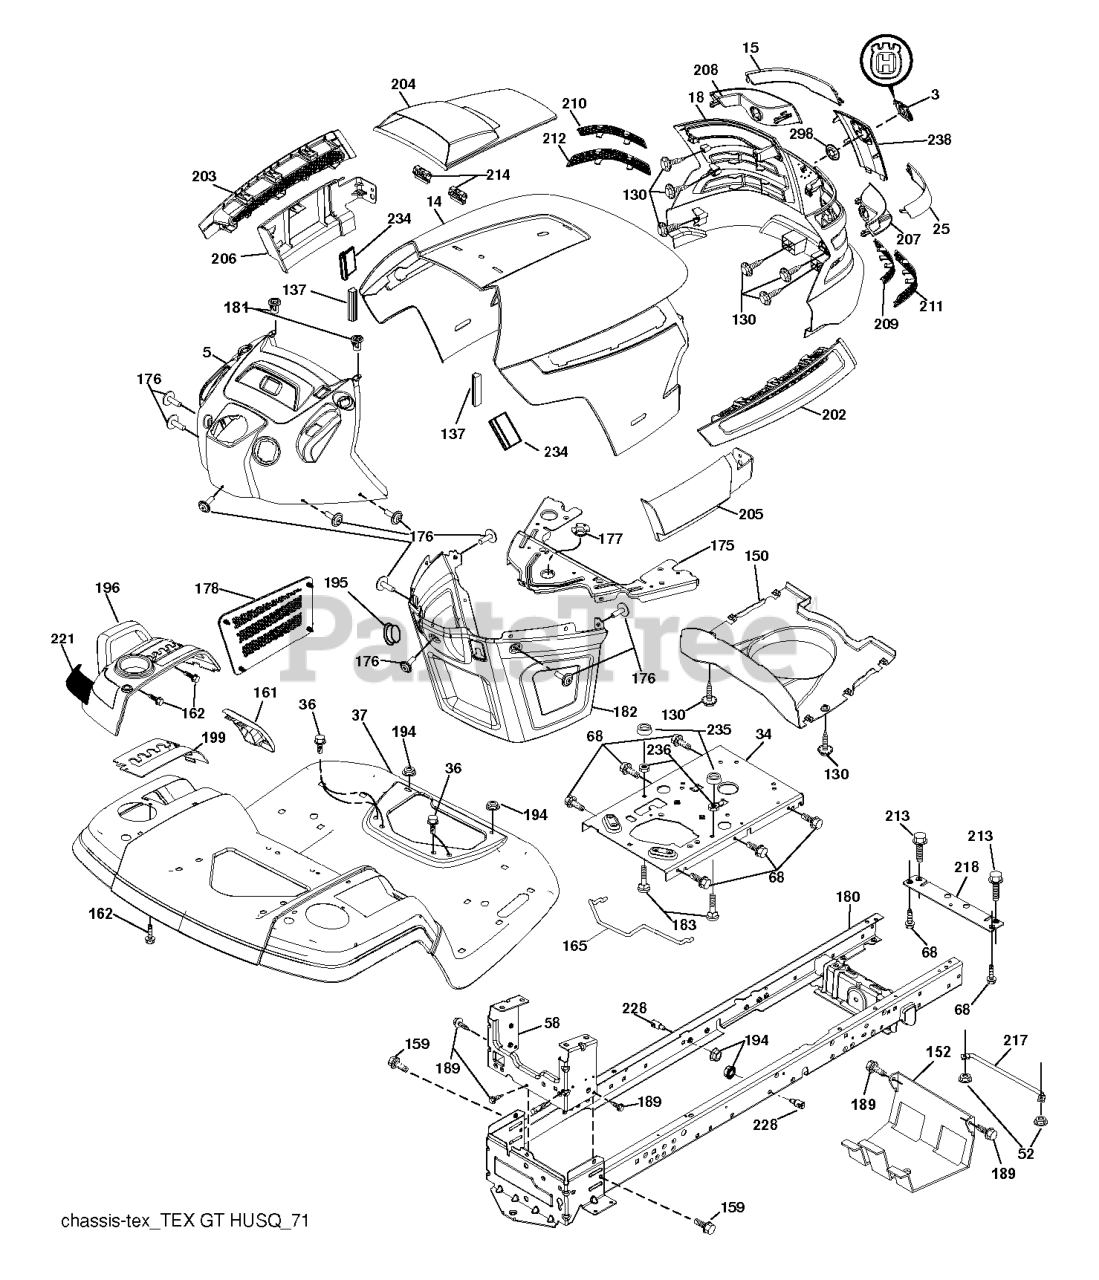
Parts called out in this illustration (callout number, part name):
3	RP LOGO
14	HOOD
15	LENS.LH.TEX.GT.HUSQ.CL
18	GRILL.ASM.HUSQ.TG/CRD.W/TRIM
25	LENS.RH.TEX.GT.HUSQ.CL
34	PLATE.ENGINE.WELDED.CHASSIS
36	SCREW 5/16"
37	FENDER.PNT.TX.GT.CH/FW.ORANGE
52	LOCKNUT
58	DRAWBAR.UPPER.2PC,LRG.FENDER
68	Screw 5/16-18 x 1/2 Hex, Self Tapping 5/16-18 x 1/2
130	SCREW.#10 X 0.750.BOS
137	BUMPER DASH
150	AIR.DUCT.HOOD.TEX.GT.HUSQ
152	SHIELD.BROWNING.W/TEX
159	SCREW, 3/8-16X3/4
161	CONSOLE.FUEL.WINDOW.HU
162	SCREW.HI-LO.CONSOLE
165	SUPPORT.TANK.REAR.W/TEX
175	PLATE.CROSSMEMBER.HUSQ
176	SCREW.#10-24X5/8.RN.QU
177	BUSHING, STEERING
178	CARGO.ASM.NET.TXGT.W/C
180	CHASS.WLDMNT.TLT.12GA/2PC.20"
181	BUSHING.MNT.FEND.CRGO.
182	DASH.LOWER.COMMON.12V.ADAPTOR
183	BOLT.5/16-18X1-1/4 FULL.THREAD
189	SCREW
194	NUT LOCK HEX FLANGE 5/16-18
195	PLUG.HOLE.DASH.LOWER.12V.BLK
196	RP CONSOLE.ASM.DECKLFT.W/
199	PLATE.DECK.LIFT.HUSQVARNA.GT
202	VENT.SIDE.HOOD.HUSQ.RH.GREY
203	VENT.SIDE.HOOD.HUSQ.LH.GRAY
204	HOOD VENT
205	SKIRT.HOOD.SIDE.HUSQ.RH.GREY
206	SKIRT.HOOD.SIDE.HUSQ.LH.GREY
207	BEZEL.RH.TEX.GT.HUSQ
208	BEZEL.LH.TEX.GT.HUSQ
209	INSERT.HEX.GRILL.HUSQ.GREY
210	INSERT.HEX.GRILL.HUSQ.
211	INSERT.HEX.GRILL.HUSQ.
212	INSERT.HEX.GRILL.HUSQ.
213	BOLT
214	CLIP.RETAINER.TINNER.
217	ROD.PIVOT.HOOD
218	X-PIECE.HOOD.STOP.NON/
221	REFLECTOR.LH.TEX GT HU
228	STUD.FASTNER.W/ANTI-ROTATE
234	BUMPER.HOOD.TEX.HUSQVARNA
235	SPACER FENDER
236	NUT.CENTERLOCK.5/16-
238	TRIM.HUSQ.TG/CRD.SERVICE
298	NUT PUSH M
